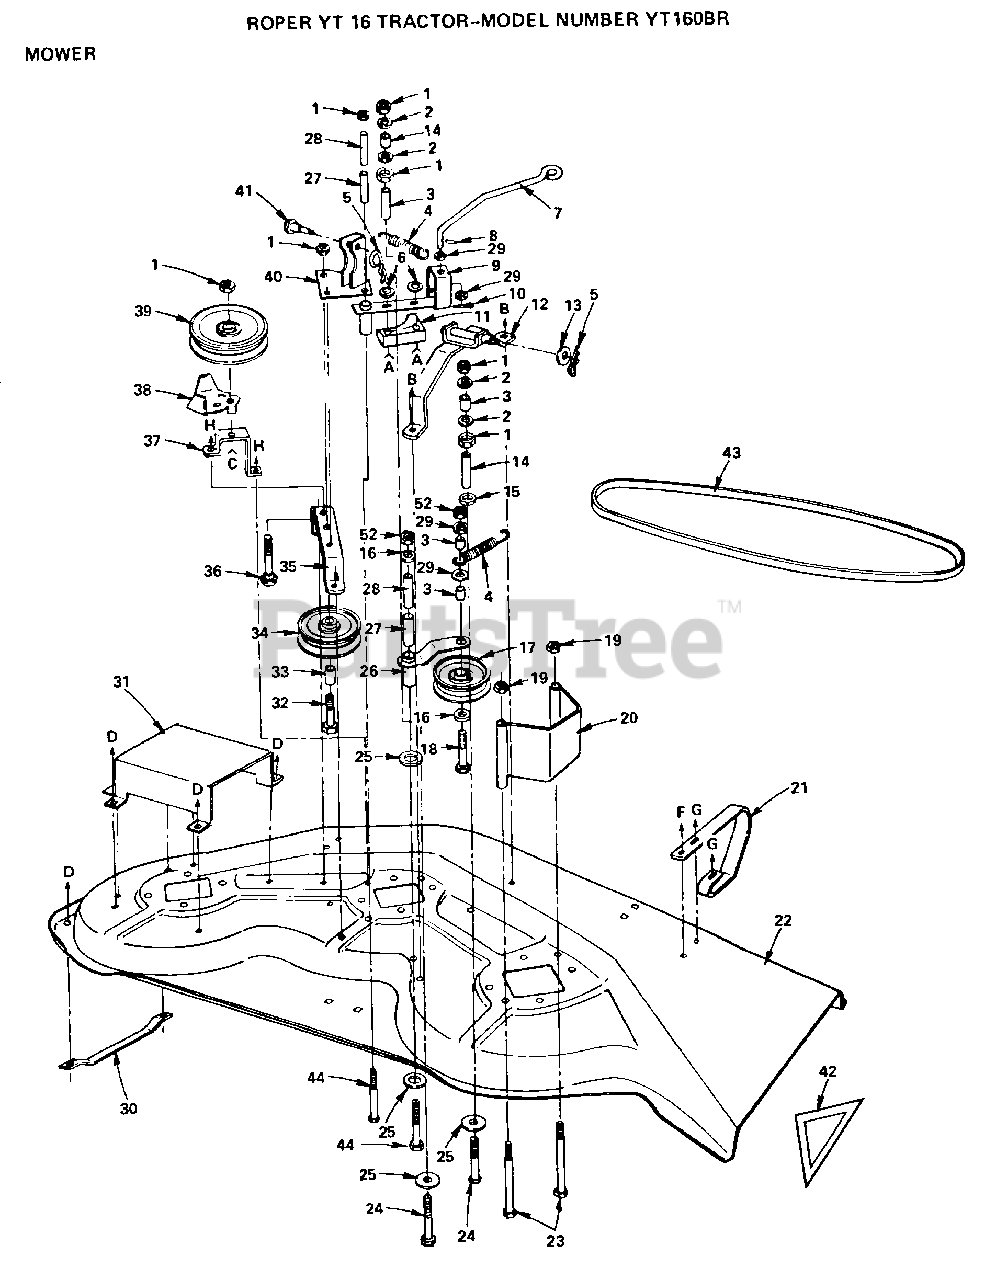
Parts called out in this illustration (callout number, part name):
2	WASHER
3	SPLIT SPACER YTV
4	SPRING T
6	WASHER
7	ROD BRAKE LTV
9	ARM ASY BRAKE Y
11	BRAKE-BLOCK YTV
12	ASSY RH LIFT YTV
14	SPACER BRAKE LTV
16	WASHER
17	IDLER.FLAT.GTV
18	BOLT
20	ASSY RH BELT GRD
23	BOLT
25	WASHER
26	ASSY IDLER ARM YT
27	"LINER YTV, BEAR."
28	BRNG-SLEEVE YTV
29	WASHER
30	RUNNER-LH M
31	GUARD-LH YTV
32	BOLT - HEX 3/8 - 16 X 3
33	SPACER-SPLIT YTV
34	IDLER-FLAT YTV
35	BRACKET IDLER YTV
36	BOLT
38	GUARD-IDLER YTV
39	IDLER-INSIDE T
44	BOLT
52	LOCKNUT
